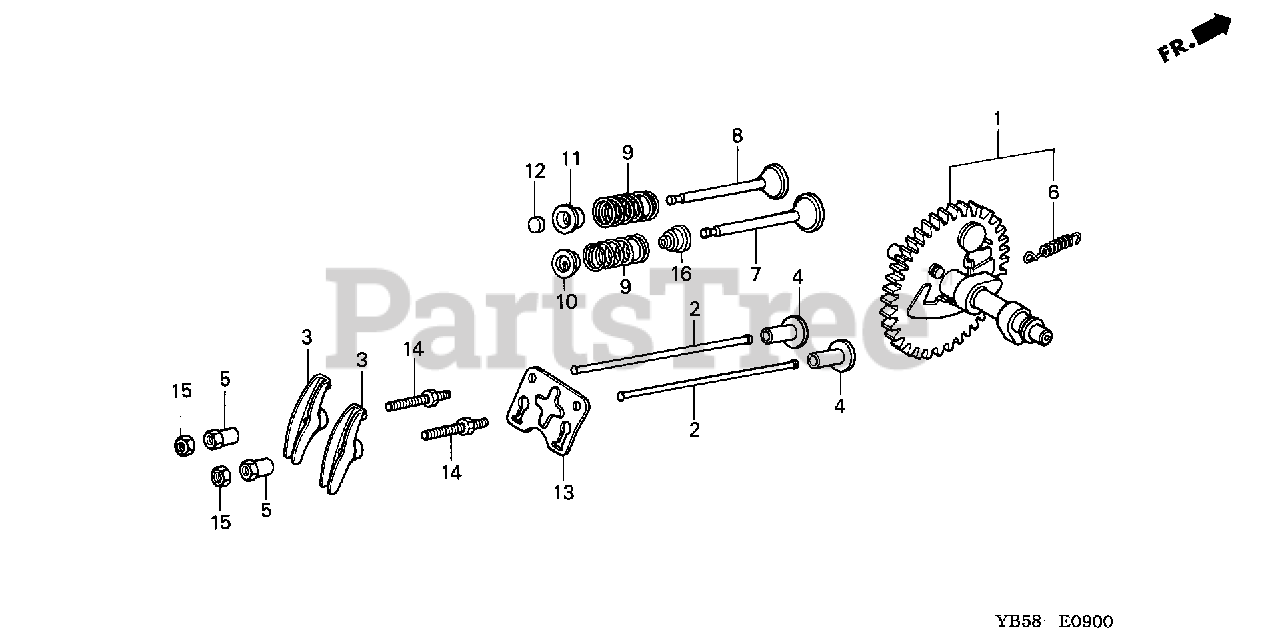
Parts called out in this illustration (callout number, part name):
1	CAMSHAFT ASSY.
2	ROD, PUSH
3	ARM, VALVE ROCKER
4	LIFTER, VALVE
5	PIVOT, ROCKER ARM
6	SPRING, WEIGHT RETURN
7	VALVE, IN.
8	VALVE, EX.
9	SPRING, VALVE
10	RETAINER, IN. VALVE SPRING
11	RETAINER, EX. VALVE SPRING
12	ROTATOR, VALVE
13	PLATE, PUSH ROD GUIDE
14	BOLT, PIVOT (8MM)
15	NUT, PIVOT ADJUSTING
16	SEAL, VALVE STEM
